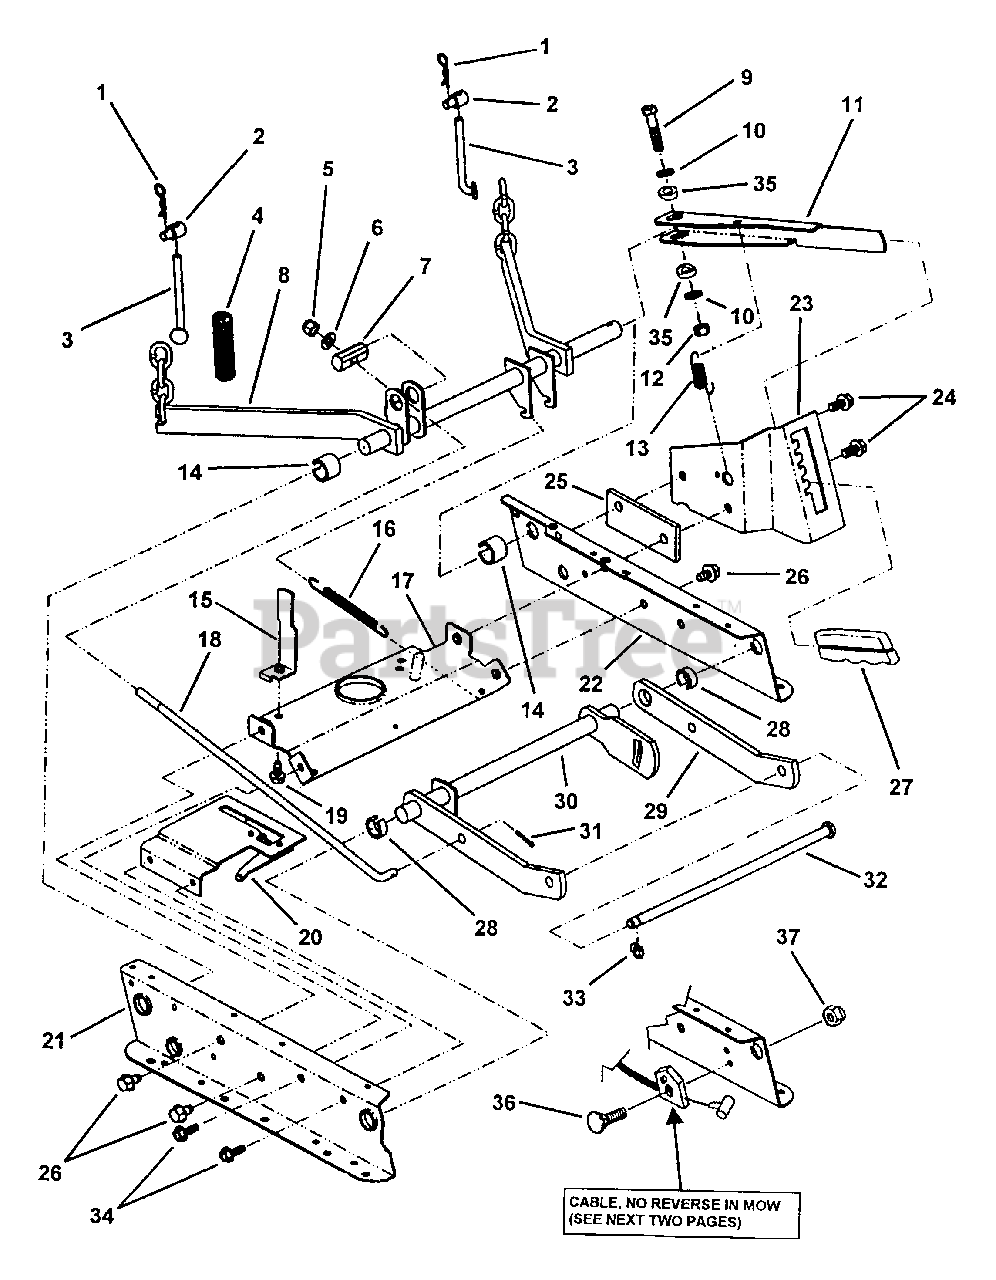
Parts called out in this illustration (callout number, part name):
1	HAIRPIN, 3/32" X 1-1/2"
2	SWIVEL
3	HOOK, Chain
4	COVER, Chain
5	NUT, 3/8-24 Hex Nyloc
6	WASHER, 3/8" Flat
7	PIVOT, Leveling
8	ARM, Rear lift
9	SCREW, 3/8-24 X 1-3/4" Hex Head Cap Grade 5
10	WASHER, 13/32- Flat
11	LEVER, Height of Cut
12	NUT, 3/8-24 Hex Center Lock
13	SPRING, Lever
14	RING, Blue
15	GUIDE, Belt
16	SPRING, Assist
17	BRACE, flap
18	ROD, Leveling
19	SCREW, 5/16-18 x 5/8" Self-Tap
20	ASSEMBLY, Clutch Plate
21	RAIL, Deck Lift, Right Hand
22	RAIL, Deck Lift, Left Hand
23	DETENT, Height Adjust
24	SCREW, 3/8-16 x 1" Hex Washer Self-Tap
25	DETENT, Spacer
26	SCREW, 3/8-16 x 5/8" Hex Washer Self-Tap
27	GRIP, Height Adjustment Lever
28	RING, Red
29	ARM, Lift
30	ARM, Front Lift (Weldment)
31	PIN, 1/8 x 314" Cotter
32	ROD, Support (Front Lift Arm to Front End)
33	SNAP RING, 7/16"
34	SCREW, 5/16-18 X 1/2" Hex Washer Self-Tap
35	SPACER, Deck Lift
36	BOLT, #10-24 x 1" Flat Head Square Neck
37	NUT, #10-24 Hex Nyloc
